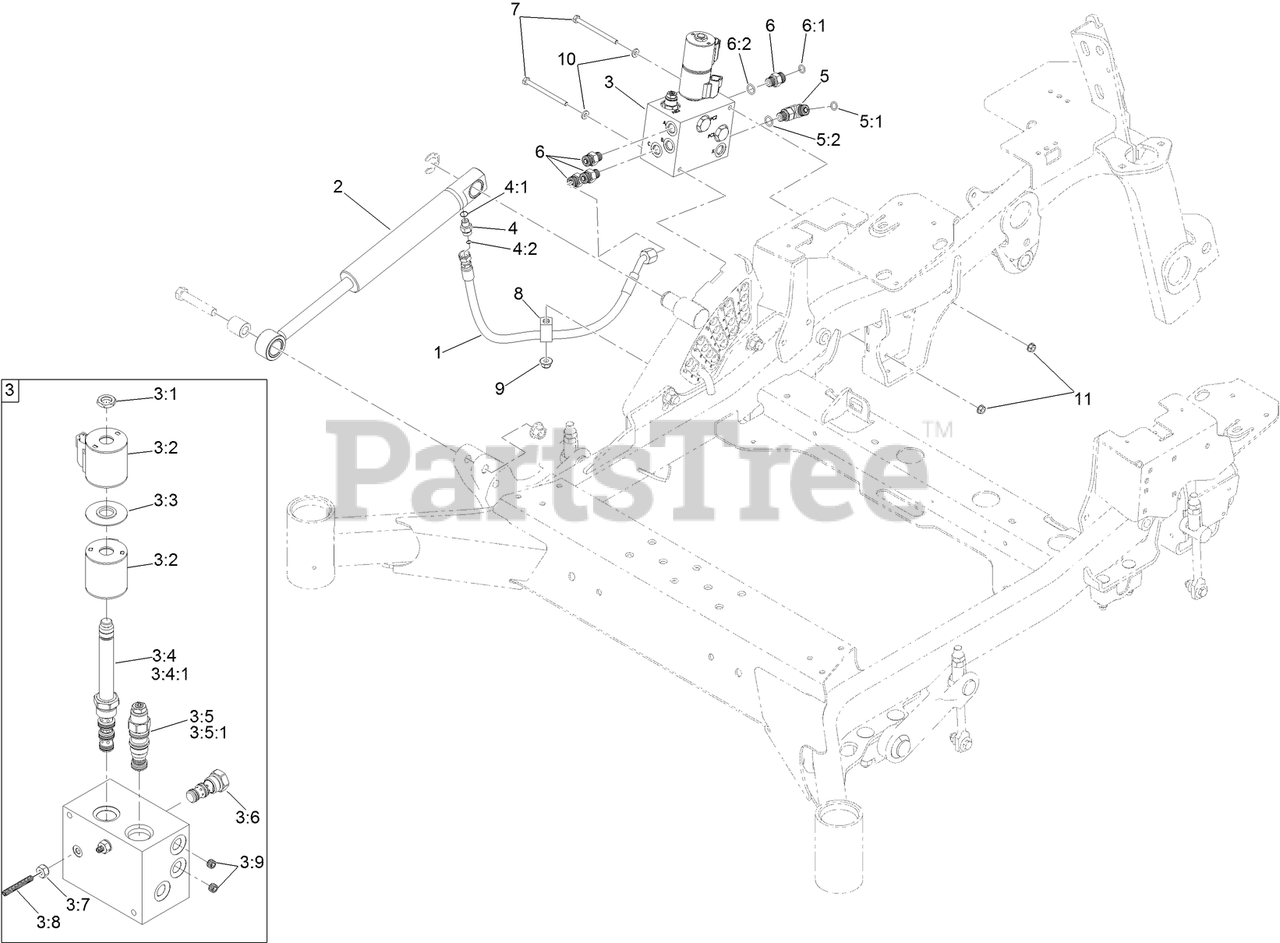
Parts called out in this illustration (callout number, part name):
1	HOSE ASM
2	CYLINDER-LIFT
3	LIFT AND HOLD VALVE ASM
3:1	NUT-COIL
3:2	COIL-12V
3:3	SPACER-E COIL
3:4	SOLENOID VALVE ASM
3:4:1	SPOOL VALVE SEAL KIT
3:5	VALVE-COUNTERBALANCE
3:5:1	SEAL KIT
3:6	VALVE-CHECK, PO
3:7	SCREW-SET
3:8	NUT-SEALING, HEX
3:9	PLUG-ORIFICE (0.020)
4	FITTING-HYD, STRAIGHT
4:1	O-RING
4:2	O-RING
5	FITTING-ELBOW, 90 DEG
5:1	O-RING
5:2	O-RING
6	FITTING-STRAIGHT
6:1	O-RING
6:2	O-RING
7	SCREW-HH
8	CLIP-LOOM
9	NUT-HF, NI
10	WASHER-FLAT
11	NUT-HF
